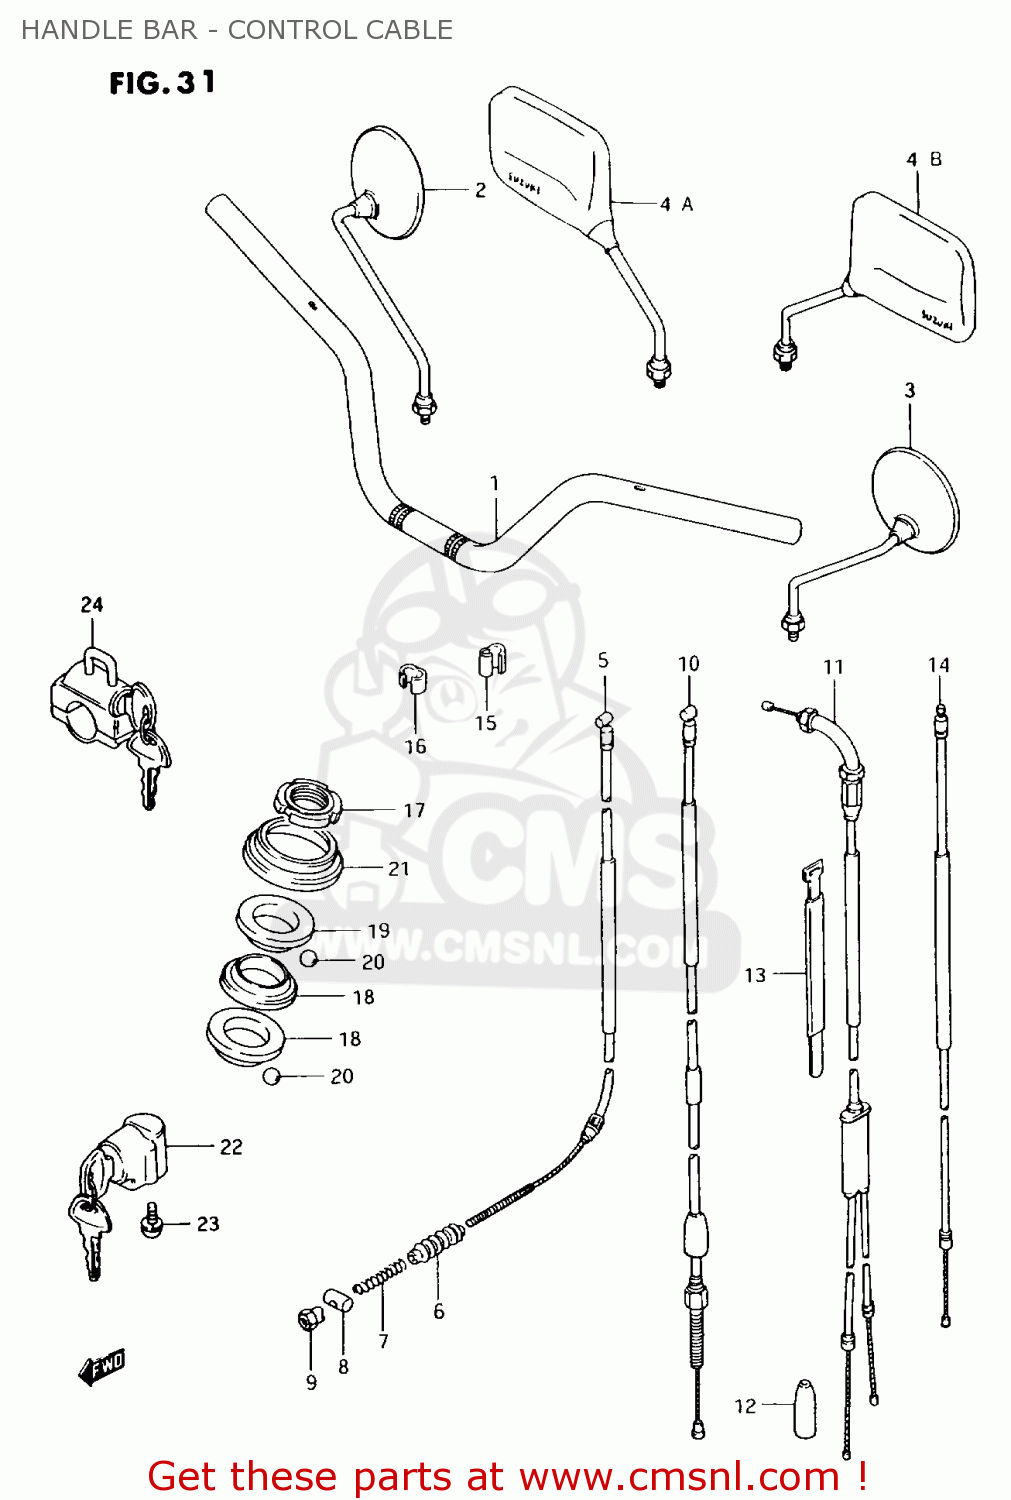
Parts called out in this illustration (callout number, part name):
1	HANDLEBAR
2	MIRROR ASSEMBLY,RIGHT
3	MIRROR ASSEMBLY,LEFT
4A	MIRROR ASSY,RR VIEW,R
4B	MIRROR ASSY, REAR VIEW LH
5	CABLE ASSY,FR BRAKE
6	SEAL,DUST(7X16X75)
7	SPRING
8	PIN,10X19
9	NUT
10	CABLE ASSY,CLUTCH
11	CABLE ASSY,THROTTLE
12	SEAL,DUST(7X18X30)
13	CLAMP(L:125)
14	CABLE,CLUTCH
15	CLIP
16	CLIP
17	NUT,STEERING STEM(25X44X10)
18	RACE,STEERING INNER UPR
19	RACE,STEERING OUTER UPR
20	BALL
21	DUST SEAL,STEERING UPR
22	LOCK ASSY,STEERING
23	SCREW
24	LOCK ASSY,HELMET
